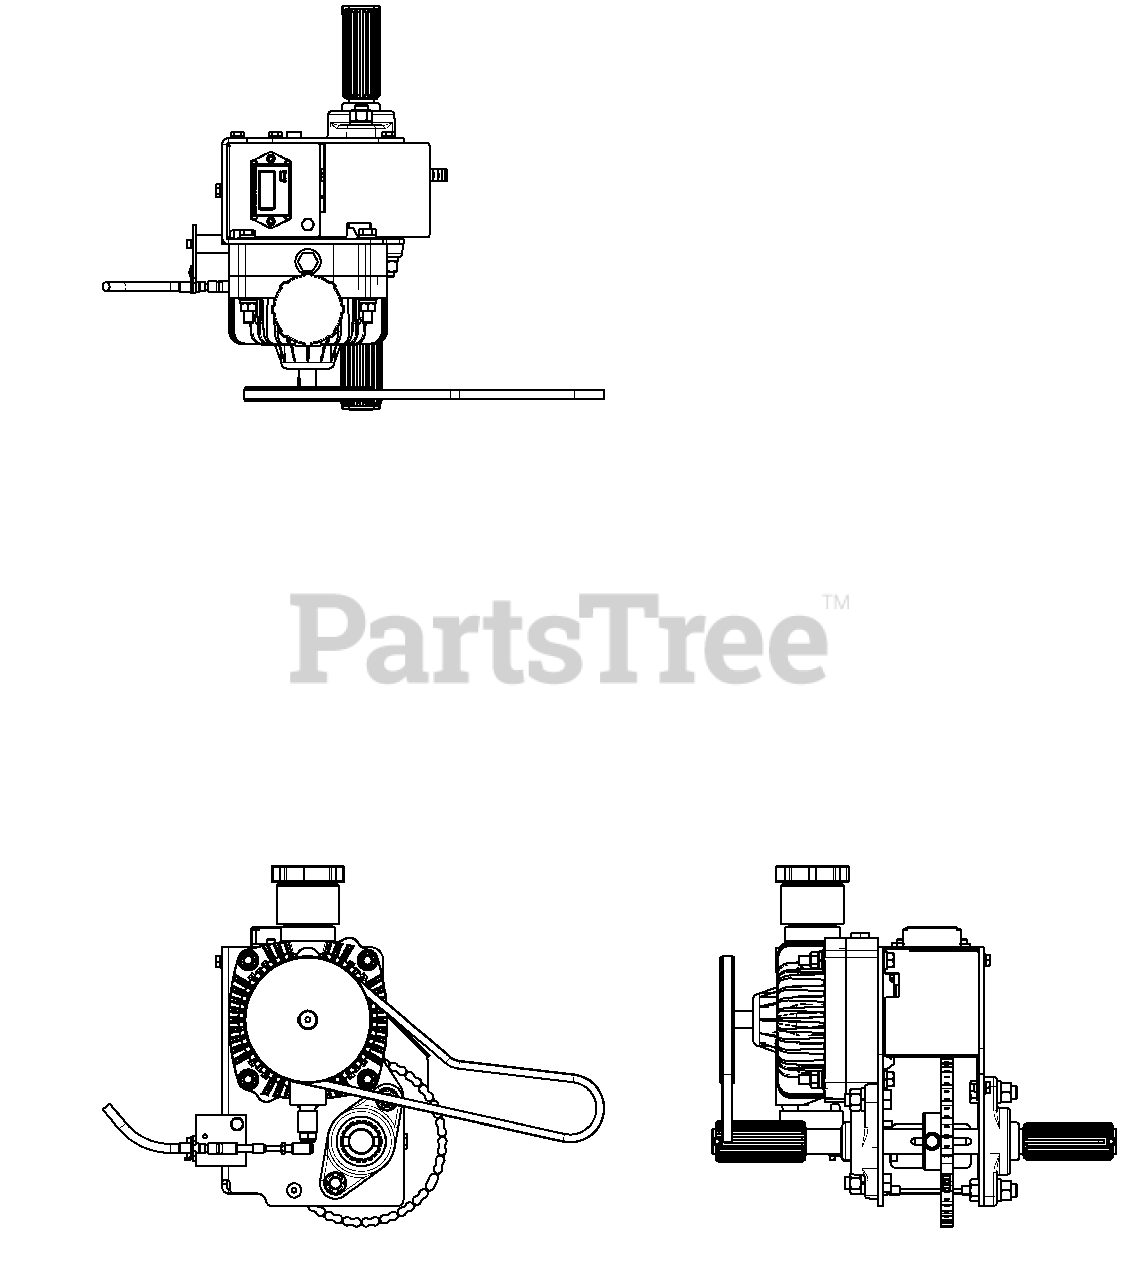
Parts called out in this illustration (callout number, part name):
1	Frame, Pump
2	Hydrostatic Pump
3	Tube, Driver, Right
4	Tube, Driver, Left
5	Sprocket, 54-Tooth
6	Chain, Roller #35
7	Connecting Link #35
8	Sprocket, 10T
9	Key, 1/4 X 1/4 X 2.00
10	Bearing, Flange, 1" Id
11	Drive Shaft
12	Sheave, 1/3V 5.00 Od X 17Mm Id
13	Cover, Pump Assembly
14	Arm, Speed Control
15	Washer, 1/4" Flat S.S.
16	Block, Cable Mount
17	Key, Woodruff, #3
18	Belt, 3L345
19	Cable, Speed Control
20	Nut, Nyloc, 3/8-16
21	Tachometer/Hour Meter
22	Cable Bracket
23	Fitting, Ball Joint
24	Nut, Nyloc, #10-32 S.S.
25	Shcs 10-32 X 1/2 S.S.
26	Washer, Split 1/4" S.S.
27	HHB 1/4-20 X .625 S.S.
28	Nut, Nyloc, 1/4-20 Cad
29	Shcs 1/4-20 X 1/2 S.S.
30	Snap Ring, Ext 1.000"
31	HHB 3/8-16 X 3.5
32	Washer, 3/8" Flat
33	Washer, 3/8"X .06"Thk Flat S.S.
34	Washer, Split 3/8" S.S.
35	Nut, 3/8-16 Hex, Gr5 Zinc
36	Shsb, 3/8 X 3/8
37	Washer, Split #10 S.S.
38	Nut, 1/2-13 Hex, Gr5 Zinc
39	Washer, Split 1/2" S.S.
40	HHB 1/2-13 X 1 1/2
41	Washer, 3/8"X .030"Thk Flat
42	Washer, 5/16" Flat S.S.
43	Washer, Split 5/16" S.S.
44	Nut, 5/16-18 Hex, S.S.
45	HHB 5/16-18 X 1
46	HHB 1/4-20 X 1 S.S.
